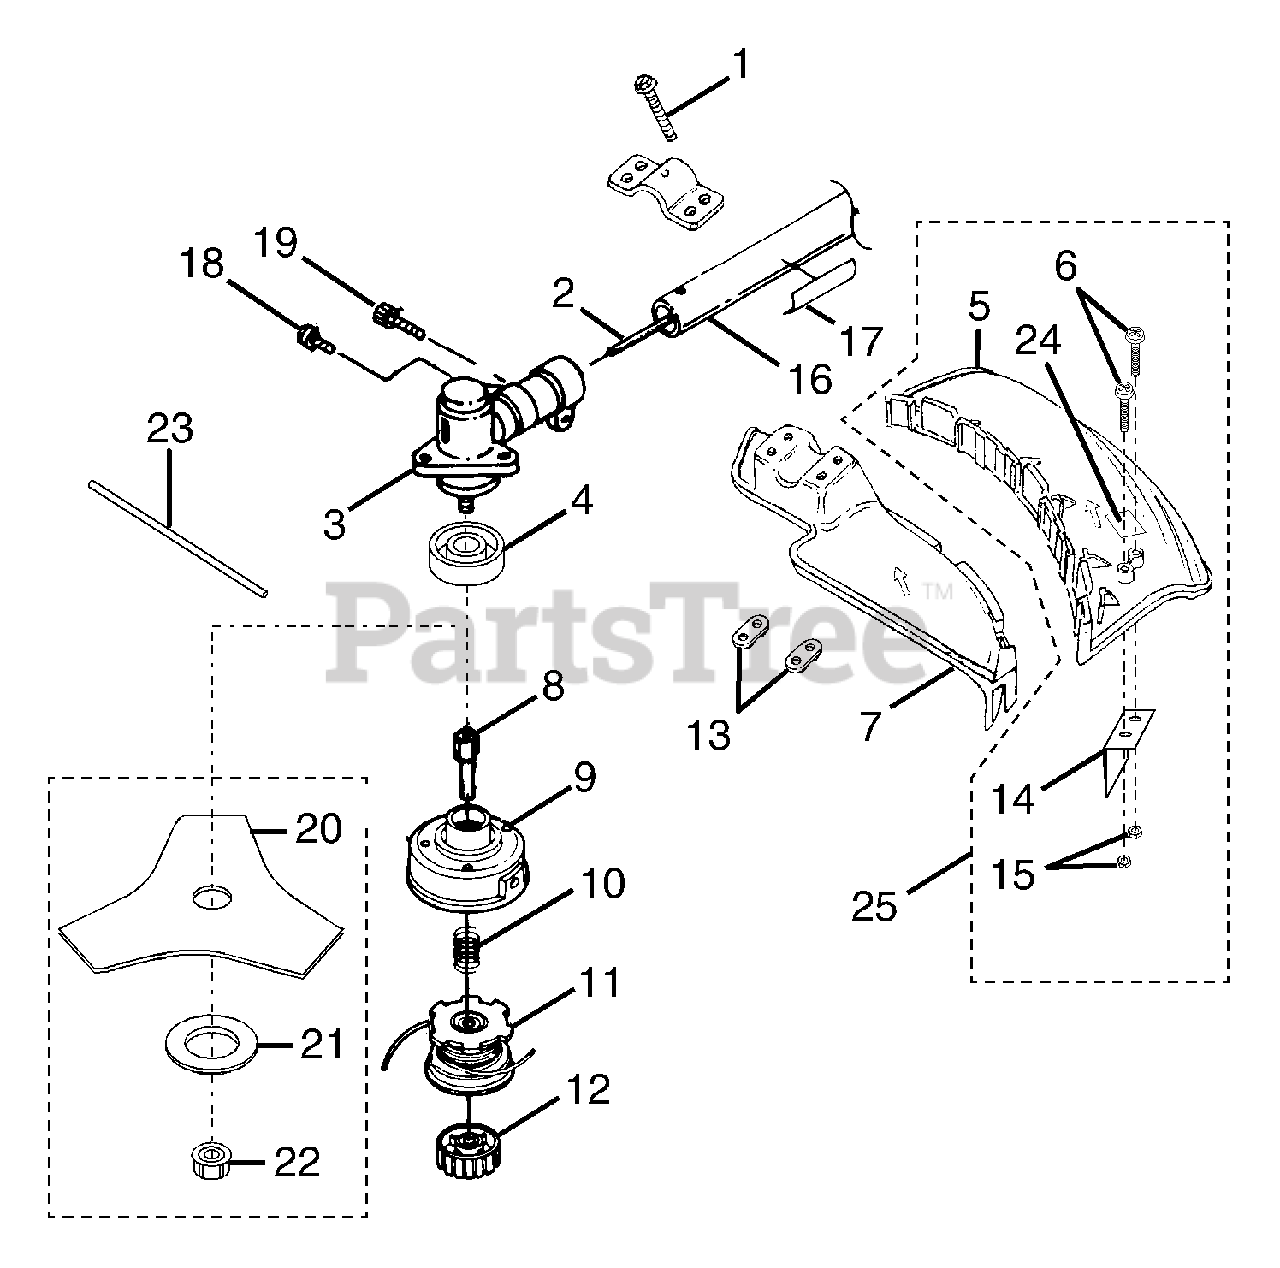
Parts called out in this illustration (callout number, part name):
2	FLEXIBLE SHAFT
3	GEAR CASE ASSEMBLY
4	FLANGED WASHER
5	STRING SHIELD CCW
6	SCREW (10 - 24 x 7/8)
7	BLADE GUARD CCW
8	ADAPTER SHAFT/1986
9	HOUSING AND EYELETS
10	COMPRESSION SPRING
11	SPOOL AND STRING (.95)
12	SPOOL RETAINER (L/H THREAD)
13	MOUNTING PLATE
14	CUT OFF BLADE
15	HEX NUT
16	D.S. HOUSING FOR BIKE HANDLE
17	WARNING DECAL
18	SCREW (10-24 x .625 TAPTIT)
19	SCREW (1/4 - 20 x 1.25 TAP)
20	TRI-ARC BLADE
21	CUPPED WASHER
22	LOCK NUT
23	HOLDING PIN
24	WARNING LABEL
25	STRING SHIELD ASSEMBLY
